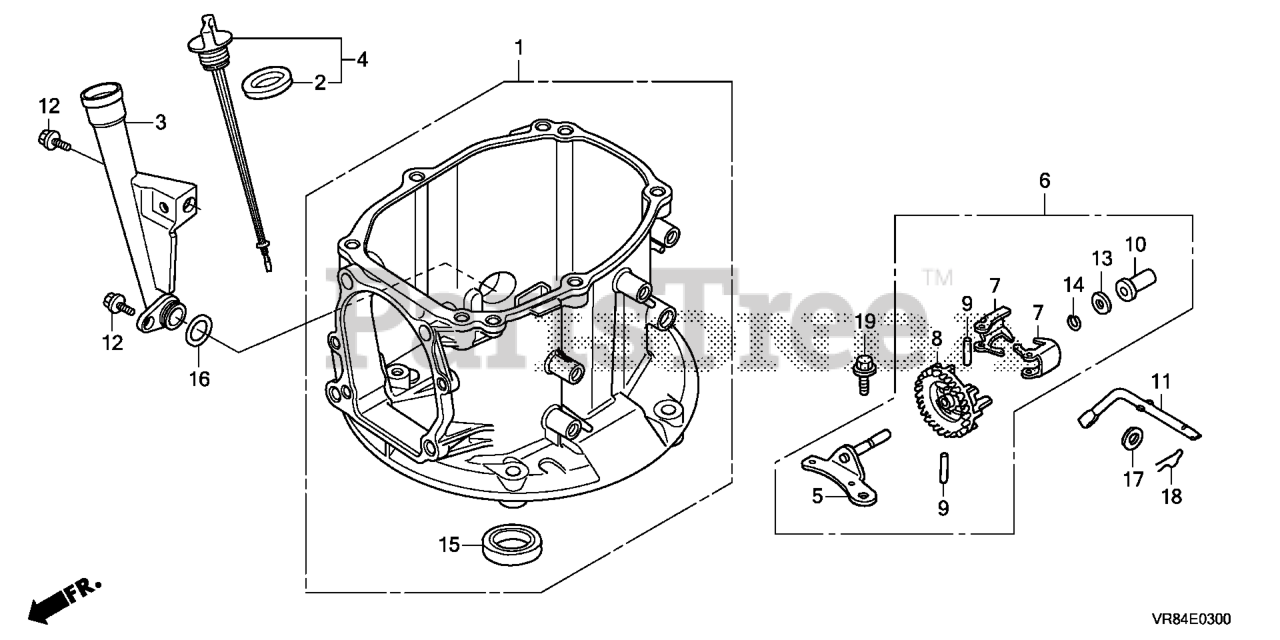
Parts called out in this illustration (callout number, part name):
1	CRANKCASE ASSY.
2	GASKET, OIL FILLER CAP Use up to Engine SN 1257294.
3	EXTENSION, OIL FILLER
4	GAUGE ASSY., OIL LEVEL
5	SHAFT, GOVERNOR HOLDER
6	GOVERNOR ASSY.
7	WEIGHT, GOVERNOR
8	HOLDER, GOVERNOR WEIGHT
9	PIN, GOVERNOR WEIGHT
10	SLIDER, GOVERNOR
11	SHAFT, GOVERNOR ARM
12	BOLT, FLANGE (6X14) (CT200)
13	WASHER, THRUST (6MM)
14	CLIP, GOVERNOR HOLDER
15	OIL SEAL (28X41.25X6)
16	O-RING (19.1X2.2)
17	WASHER, PLAIN (6MM)
18	PIN, LOCK (8MM)
19	BOLT, FLANGE (6X14)
